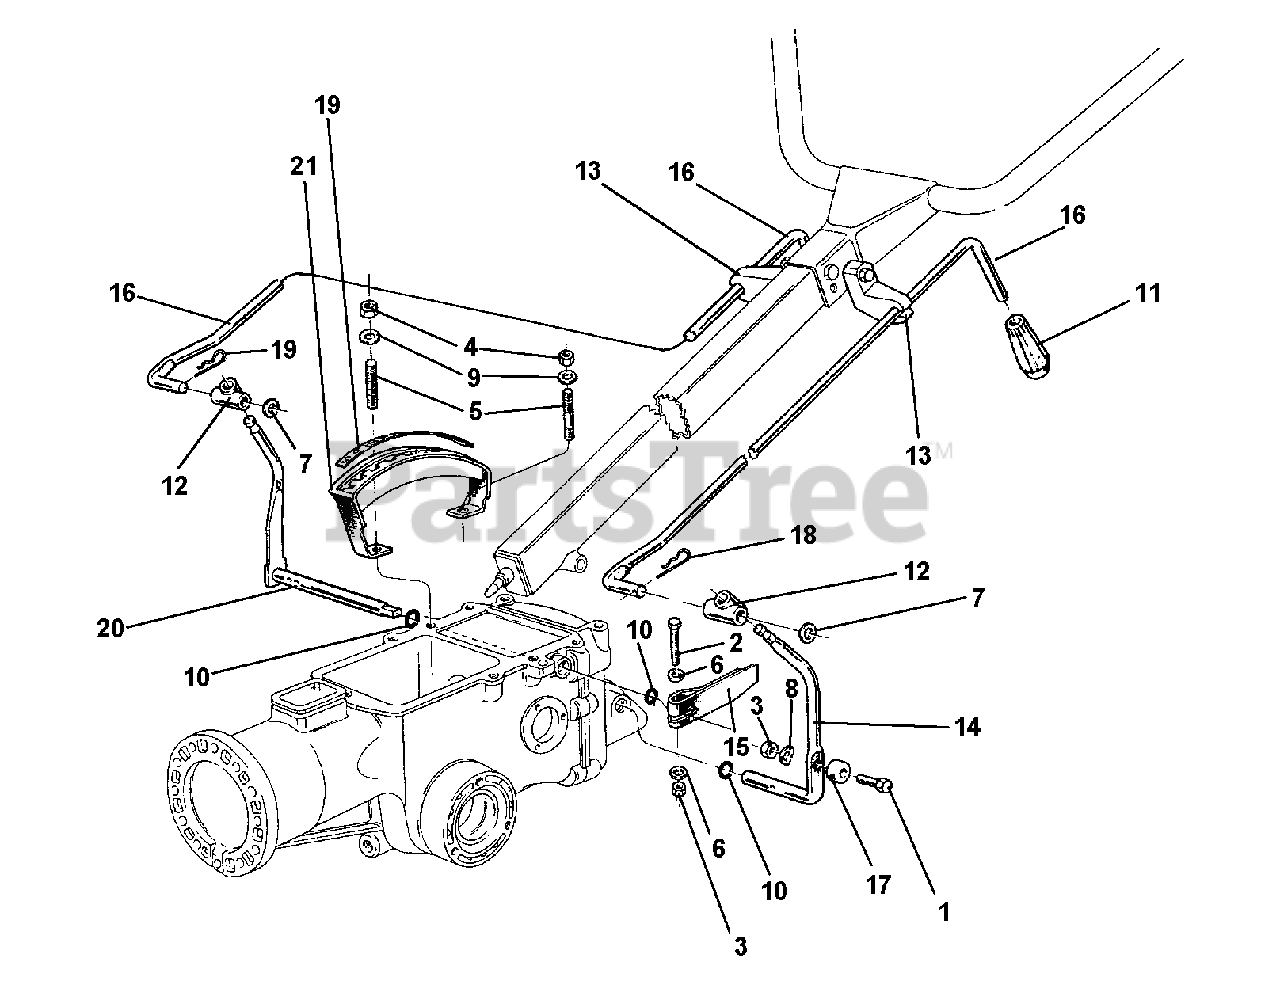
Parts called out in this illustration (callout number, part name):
1	SCREW M6 X 25
2	SCREW M6 X 35
4	NUT, SELF LOCKING M8
5	STUD M8 X 38 X 14 X 20
6	WASHER, FLAT 6.4
7	WASHER P10.5 X 18
8	WASHER, LOCK 6.4
9	WASHER, LOCK 8.4
10	O-RING 115 11.91 X 2.62
12	JOINT, D 10
13	SUPPORT CONTROL ROD CUT
14	P.T.O. LEVER
15	STOP, REVERSE
16	ROD, CONTROL POWER TILLER
19	PLATE, SPEED, POWER TILLER
20	GEARBOX LEVER
